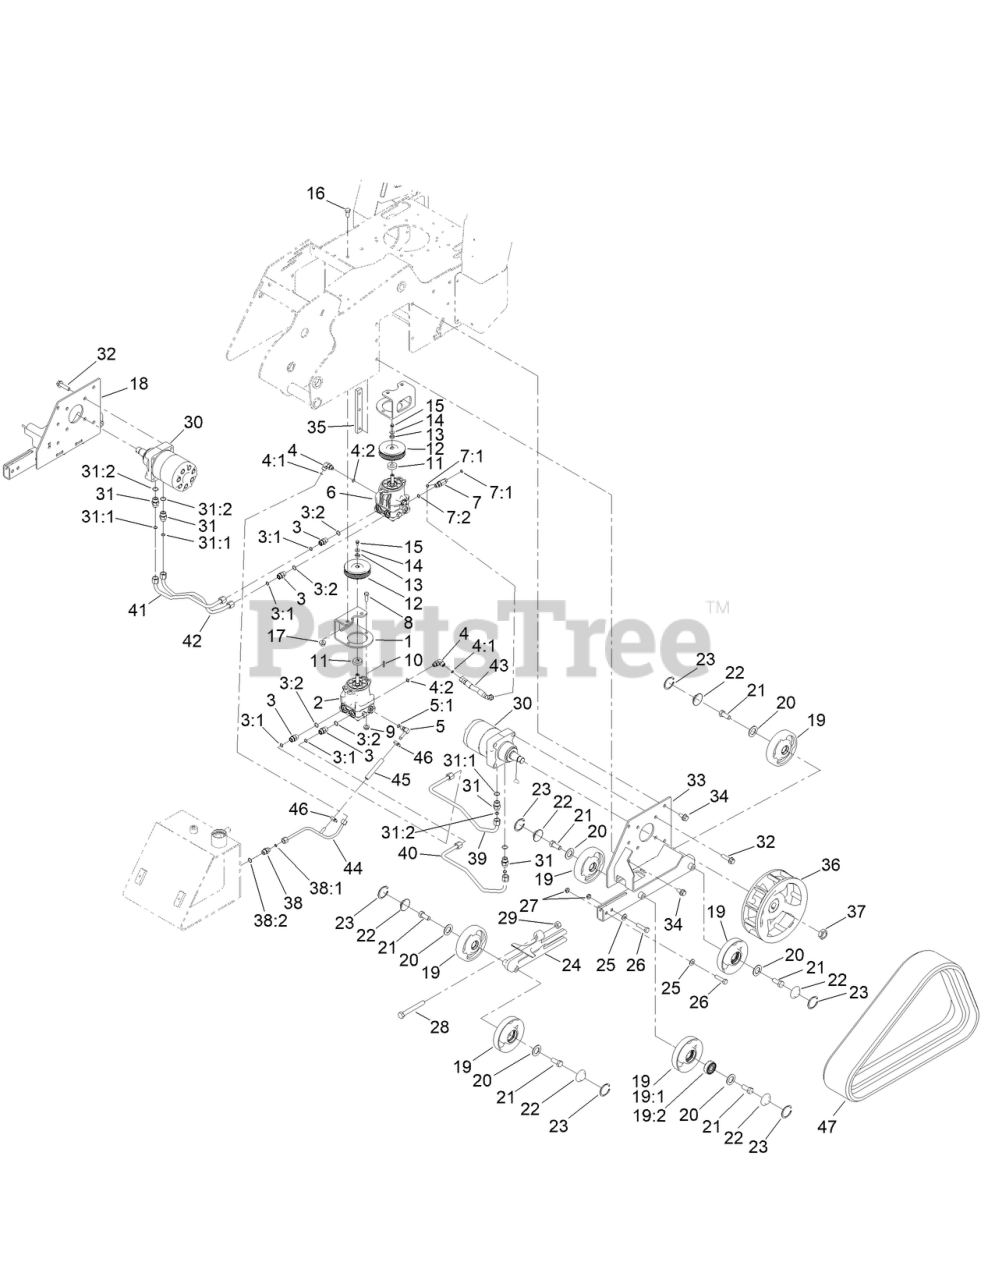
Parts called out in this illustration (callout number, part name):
1	BRACKET-MOUNT, PUMP
2	RH HYD PUMP ASM
3	FITTING-STRAIGHT
3:1	O-RING
3:2	O-RING
4	FITTING-ELBOW, 90 DEG
4:1	O-RING
4:2	O-RING
5	FITTING-ELBOW, 90
5:1	O-RING
6	LH HYD PUMP ASM
7	FITTING-TEE
7:1	O-RING
7:2	O-RING
8	SCREW-HH
9	NUT-HF
10	KEY-PUMP
11	SPACER
12	SHEAVE
13	BUSHING
14	WASHER
15	SCREW-HHF
16	SCREW-HH
17	NUT-HHF
18	FRAME-TRACK, RH
19	TENSIONER WHEEL ASM
19:1	WHEEL-TRACK
19:2	BEARING-BALL
20	GASKET-BOGIE
21	SCREW-HH
22	CAP-WHEEL, BEARING
23	RING-SNAP, INTERNAL
24	TENSIONER-TRACK
25	WASHER-FLAT
26	SCREW-HH
27	NUT-HEX
28	SCREW-HH, TAP
29	NUT-HEX
30	HYD WHEEL MOTOR ASM
31	FITTING-STRAIGHT
31:1	O-RING
31:2	O-RING
32	SCREW-HHF
33	FRAME-TRACK, LH
34	SCREW-HHF
35	BAR-THREAD
36	WHEEL-DRIVE
37	NUT-LOCK
38	FITTING-STRAIGHT
38:1	O-RING
38:2	O-RING
39	TUBE-HYD
40	TUBE-HYD
41	TUBE-HYD
42	TUBE-HYD
43	HOSE-HYD
44	TUBE-HYD
46	CLAMP-HOSE
47	TRACK-RUBBER
